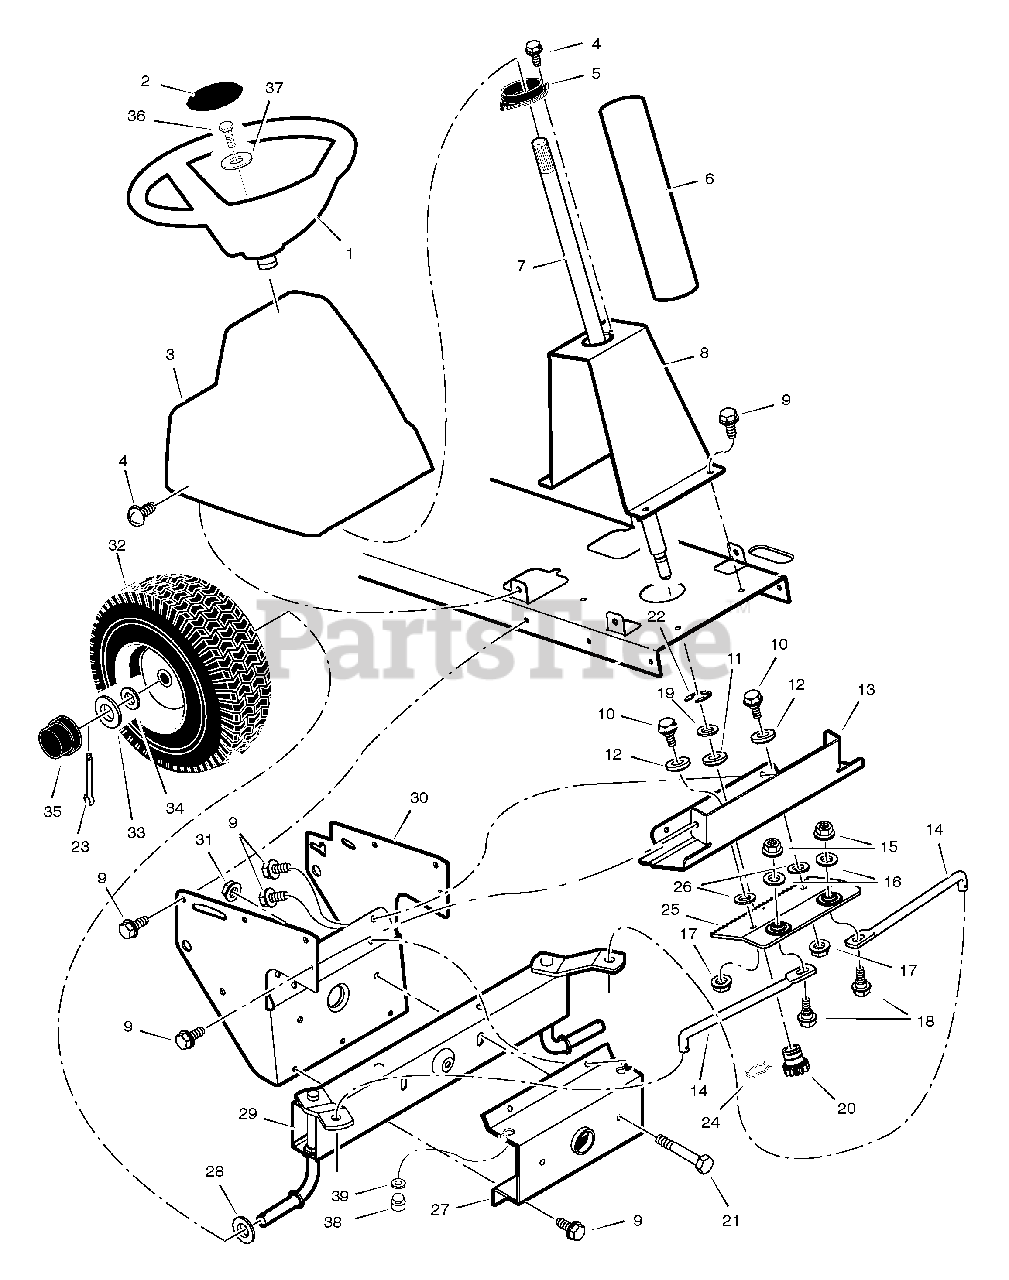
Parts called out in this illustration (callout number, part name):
1	Wheel, Steering
2	Insert, Steering
3	Console, Low -Black
4	Screw
5	Bearing, Upper Steering
6	Tube, Steering
7	Shaft, Steering
8	Support, Steering
10	Bolt, Shoulder
11	Bearing, Lower Steering
13	Plate, Gear Mounting
14	Link, Drag
15	Nut, Flange
16	Washer
17	Nut, Flange
18	Bolt, Hex
19	WASHER, 1-1.3 16G FLT
20	Gear, Pinion
21	Bolt, Hex
22	E-Ring, Retainer
23	Pin, Cotter
24	Retainer, Spring
25	Rack, Steering
27	Bracket, Axle Front
28	Washer
29	Axle & Spindle Assembly
30	Bracket, Support
31	Nut, Flange
32	Wheel, Front
34	Washer
35	Cap, Hub
36	Screw, Hex
37	Washer
38	Bumper, Rubber
